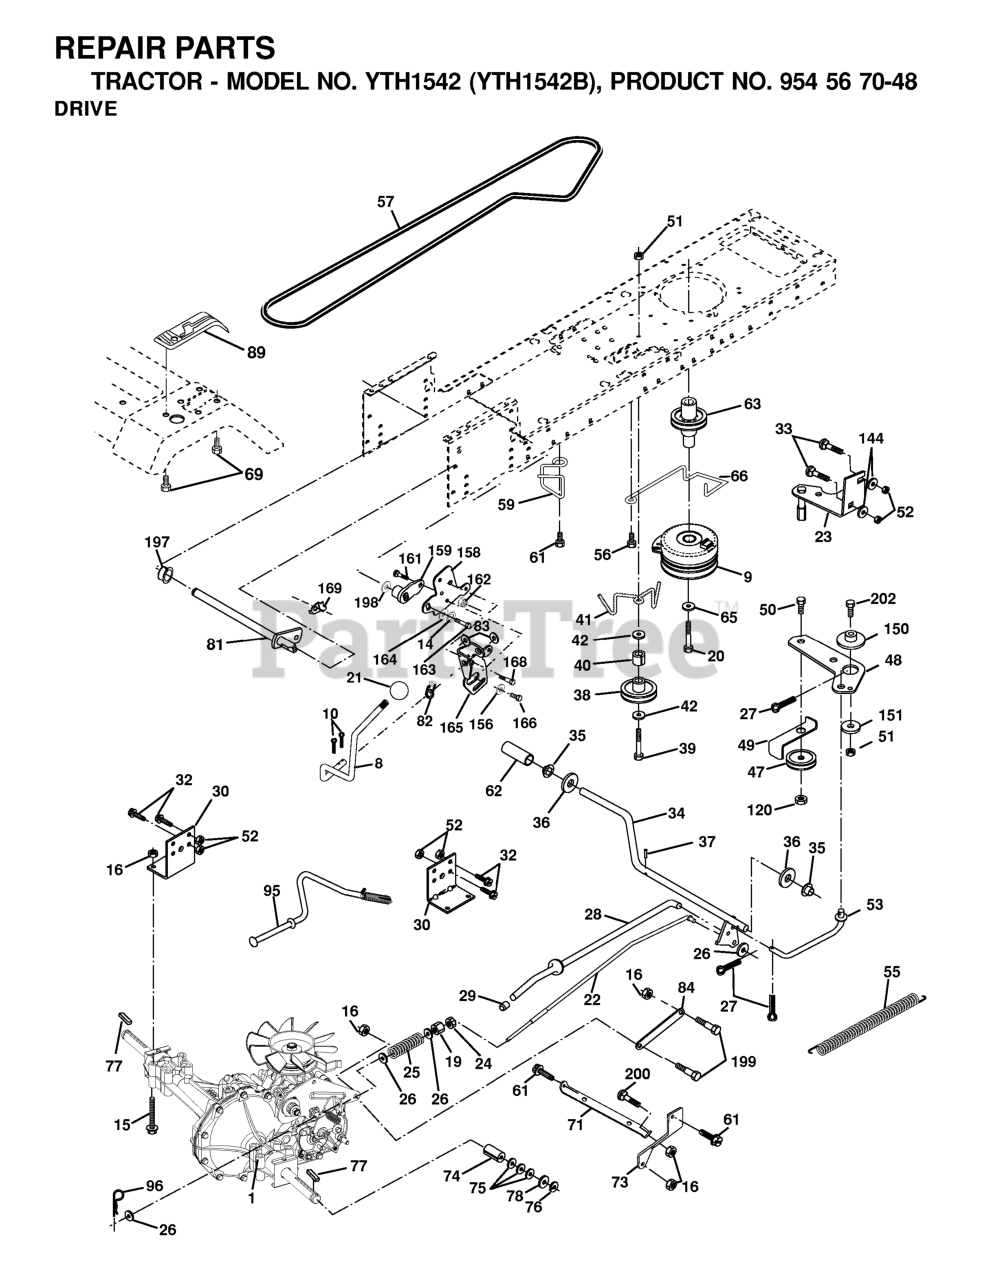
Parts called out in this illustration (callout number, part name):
8	ROD.SHIFT.FENDER.ADJ.LT.CRD
9	CLUTCH.ELECT.EVX.
10	PIN COTTER
14	LOCKWASHER
15	BOLT HEX 5/16-18 GR 5
16	NUT.71038.31-18.HEX.NYLOCK
19	NUT
20	BOLT HEX
21	KNOB.DELUXE.(PISTOL.GRIP).BLAC
22	ROD BRAKE HYDRO
24	NUT
25	SPRING ROD LT
26	WASHER
27	COTTER PIN
28	ROD, PARKING BRAKE
29	PLUNGER CAP
30	BRKT, TRNSXLE MNT 20"
32	BOLT
33	RP BOLT 5/16-18 X3/4 ZN/YEL GR
34	SHAFT, FOOT PEDAL
35	BEARING.NYLON
37	DRIVE PIN
38	PULLEY.FLAT
39	BOLT
40	SPACER, SPLIT
41	KEEPER, BELT IDLER
42	WASHER
47	IDLER PULLEY
48	BELLCRANK, CLUTCH
49	RETAIN BELT
50	BOLT
52	LOCKNUT
53	LINK, CLUTCH LT
55	SPRING, RETURN LT
56	SCREW THDROL 3/8-16 X 1-1/2
57	DRIVE BELT, LTH & YTH TRACTORS
59	KEEPER, BELT CENTER
61	SCREW 3/8-16X3/4
62	PEDAL COVER T
63	PULLEY, ENGINE
65	LOCKWASHER
66	KEEPER BELT ENGINE
69	SCREW.HI-LO.CONSOLE
71	STRAP TORQUE LH HYDRO
73	STRAP TORQUE RH HYDRO
74	SPACER AXLE
77	SQUARE KEY
81	SHAFT ASM CROSS TAPERED
82	SPRING,TORSION
83	WASHER
84	LINK TRANSAXLE
89	CONSOLE, SHIFT
95	CONTROL ASM. BYPASS HYDRO
96	RETAINER M
120	NUT LOCK FLG 3/8-16 UNC
144	Washer 11/32 x 5/8 x 16 Ga SD
150	SPACER, RETAINER
151	WASHER 12/32X2X10GA
156	WASHER.SRRTD.5/16
158	BRACKET
159	HUB
161	BOLT
162	NUT.CROWNLOCK.1/4
164	Washer 5/8 x .281 x 10 Ga.
165	RP BRACKET
168	BOLT.SHOULDER.5/16-18X
169	PLATE.FASTENING.CROSS.SHAFT
197	NYLINER SNAP 5/8" ID
198	WASHER.NYL.7/8IDX.105"HYD CR
199	BOLT SHOULDER 5/16-18 UNC
202	BOLT.3/8-16X1.50
